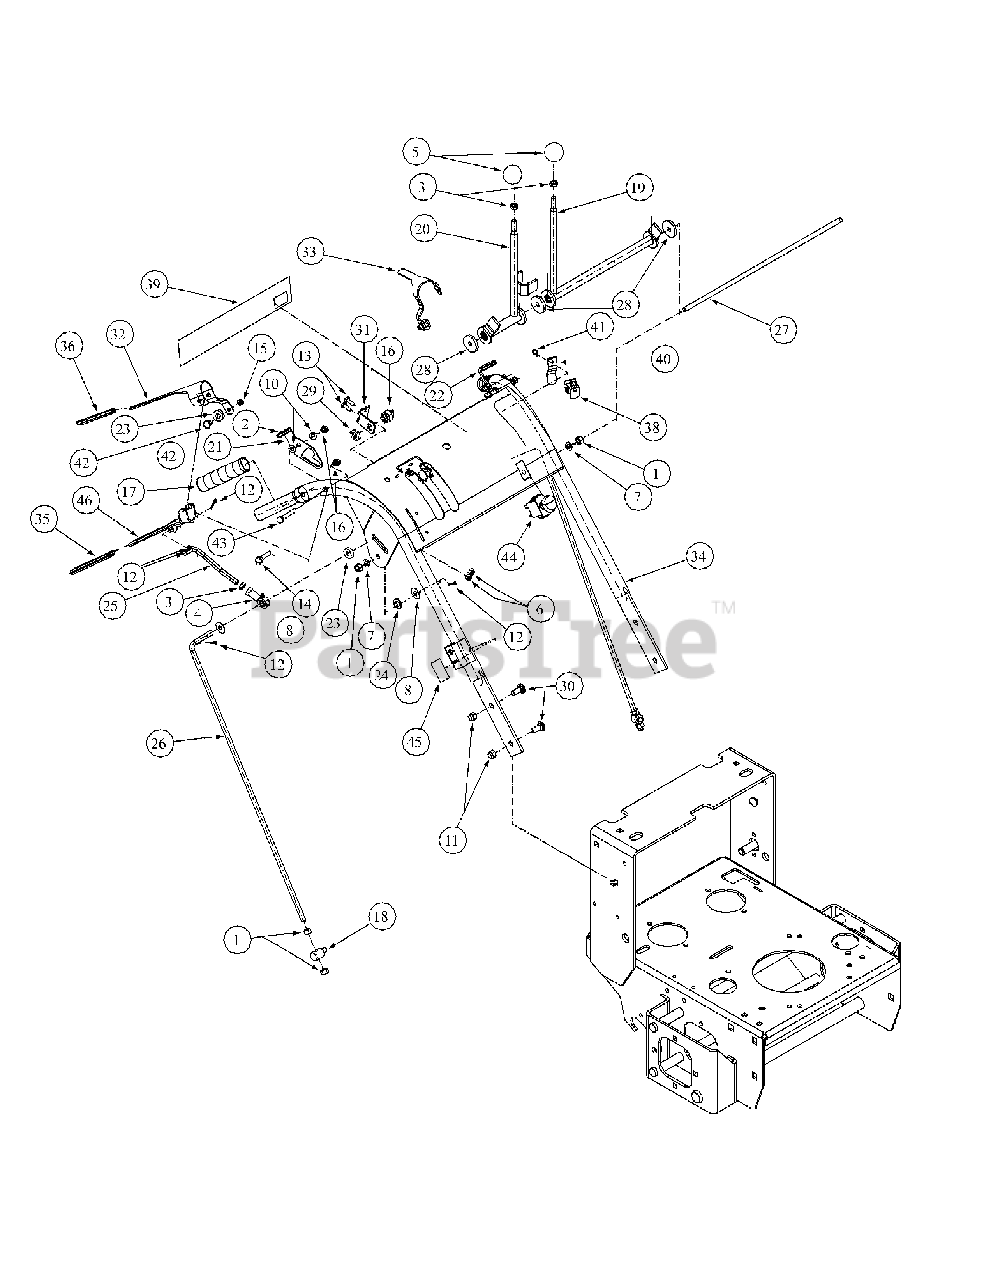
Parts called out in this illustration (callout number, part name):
1	Hex Nut, 3/8-16
2	Grip, Neutral Latch, 1.25", Black
3	Hex Nut, Jam 3/8-24
4	End Rod, 3/8 Female
5	Knob, 1-3/8 x 1-19/64, 3/8-24
6	Lock Nut, Nylon Insert, 1/4-20
7	Lock Washer, 3/8
8	Flat Washer, 3/8
9	Nut, 5/16-18
10	Flat Washer, 5/16
11	Lock Nut, Nylon Insert, 3/8-16
12	Cotter Pin, 3/32 x 1/2
13	HHCS, 1/4-20, .75
14	HHCS, Standard, 5/16 -18 x 2
15	Lock Nut, SS, Nylon Insert, 1/4-28
16	Operator Presence Switch
17	Grip, 4-5/8, Black, Plastic Handle
18	Pivot Belt Tightener
19	Control Assembly, Speed, Hydro LH
20	Control Assembly, Speed, Hydro RH
21	Latch, RH Neutral Hydro
22	Latch, LH Neutral Hydro
23	Hydro Spacer Control Rod
24	Hydro Bushing Control Rod
25	Control Rod Short Hydro
26	Control Rod Long Hydro
27	Hydro Rod Speed Control
28	Friction Washer
29	Hex Nut, Dead Man Switch
30	Carriage Bolt, 3/8-16 x 2
31	Neutral Safety Mounting Switch
32	Operator's Presence Control, RH
33	Operator's Presence Control, LH
34	Hydro Handle Assembly
35	Control Sleeve, Black
36	Operator's Presence Sleeve, Yellow
37	Harness Assembly Adapter
38	Snap Mounting Switch
39	Label Handle
40	Retension Spring
41	Screw, TT, 10-24, .500, HXINDWSH
42	Shoulder Screw, .38 x .412, 1/4-28
43	HHCS, 5/16-18, 2.00
44	Switch, Electric PTO
45	Decal, Parking Brake
46	Control Lever Assembly
